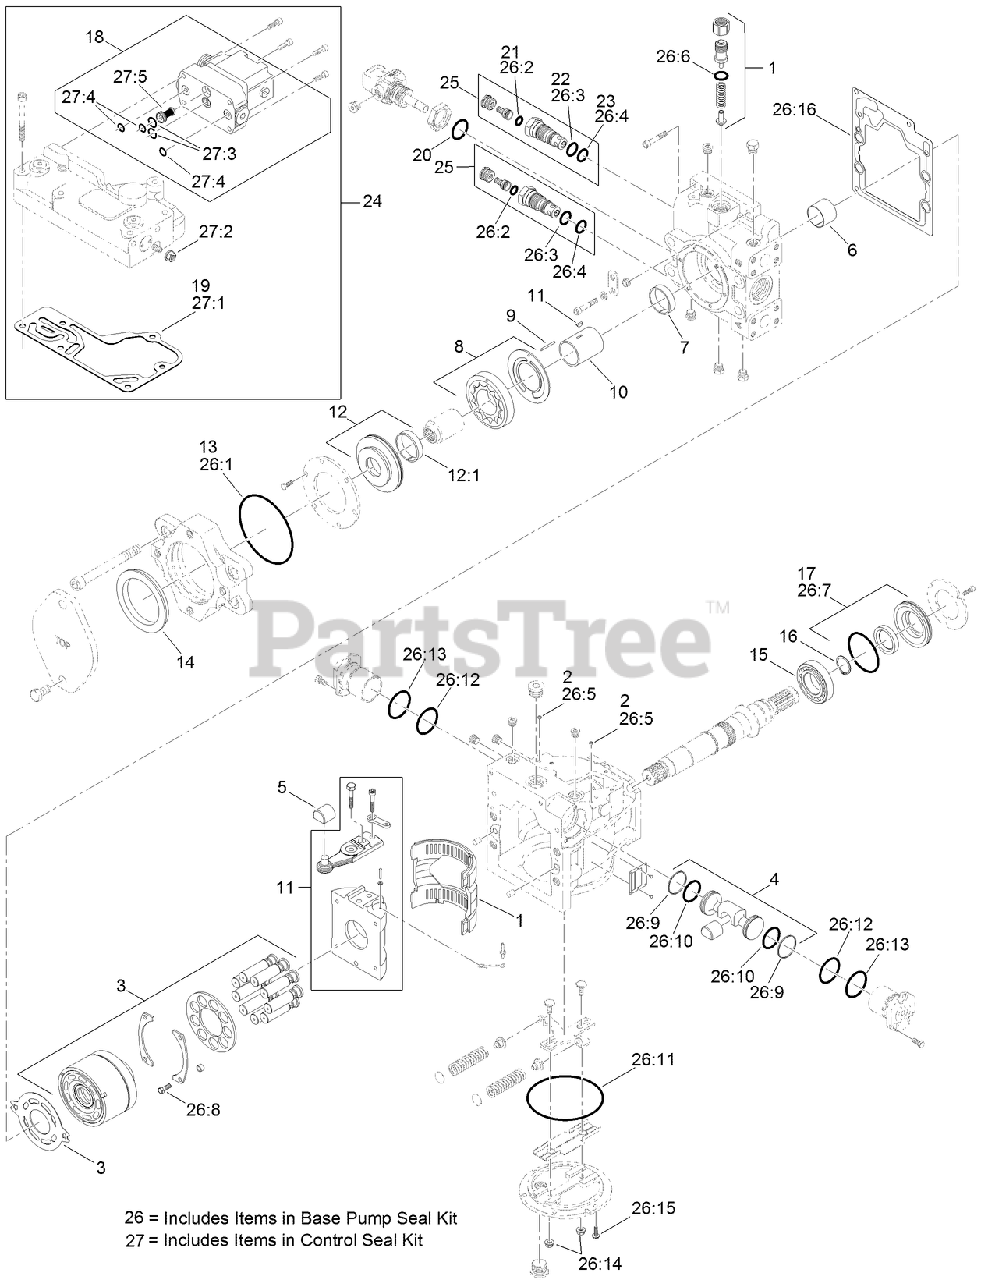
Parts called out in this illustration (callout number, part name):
1	BEARING ASM
2	SCREEN-FILTER, CONTROL
3	PLATE-VALVE
4	SERVO PISTON KIT
5	BLOCK-SLIDER
6	BEARING-JOURNAL
7	BUSHING
8	CHARGE PUMP SET
10	CHARGE PUMP SHAFT
12	CHARGE PUMP COVER ASM
12:1	BUSHING
14	SEAL-B PAD
15	BEARING-ROLLER
16	RING-RETAINING
17	SHAFT SEAL ASM
18	WEATHER PACK CONNECTOR KIT
19	GASKET-CONTROL
20	O-RING
21	O-RING
22	O-RING
23	O-RING
24	EDC KIT
25	MULTI-FUNCTION VALVE KIT
26	BASE PUMP SEAL KIT
26:2	O-RING
26:3	O-RING
26:4	O-RING
26:5	SCREEN-CONTROL FILTER
26:6	O-RING
26:7	SHAFT SEAL ASM
26:8	Screw
26:9	O-RING
26:10	O-RING
26:11	O-RING
26:12	O-RING
26:13	O-RING
26:14	NUT
26:15	Screw
26:16	Gasket-End Cap
27	CONTROL SEAL KIT
27:1	GASKET-CONTROL
27:2	NUT-SEAL
27:3	O-Ring
27:4	O-Ring
27:5	FILTER ASM
